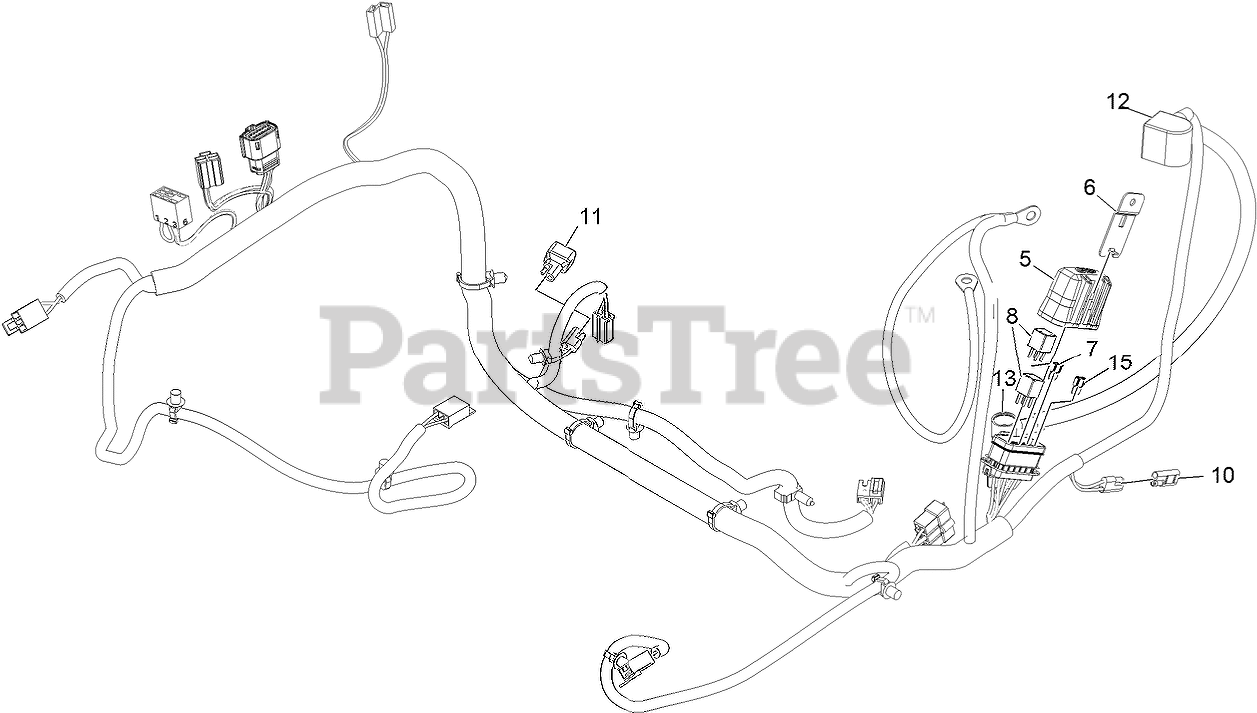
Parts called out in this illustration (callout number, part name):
5	COVER-BLOCK, FUSE
6	CLIP-MOUNTING
7	FUSE-MINI BLADE, 20 AMP
8	RELAY-MICRO
10	CAP-PLUG
12	INSULATOR-BATTERY
13	INSULATOR-SOLENOID
15	FUSE-MINI BLADE, 15 AMP
